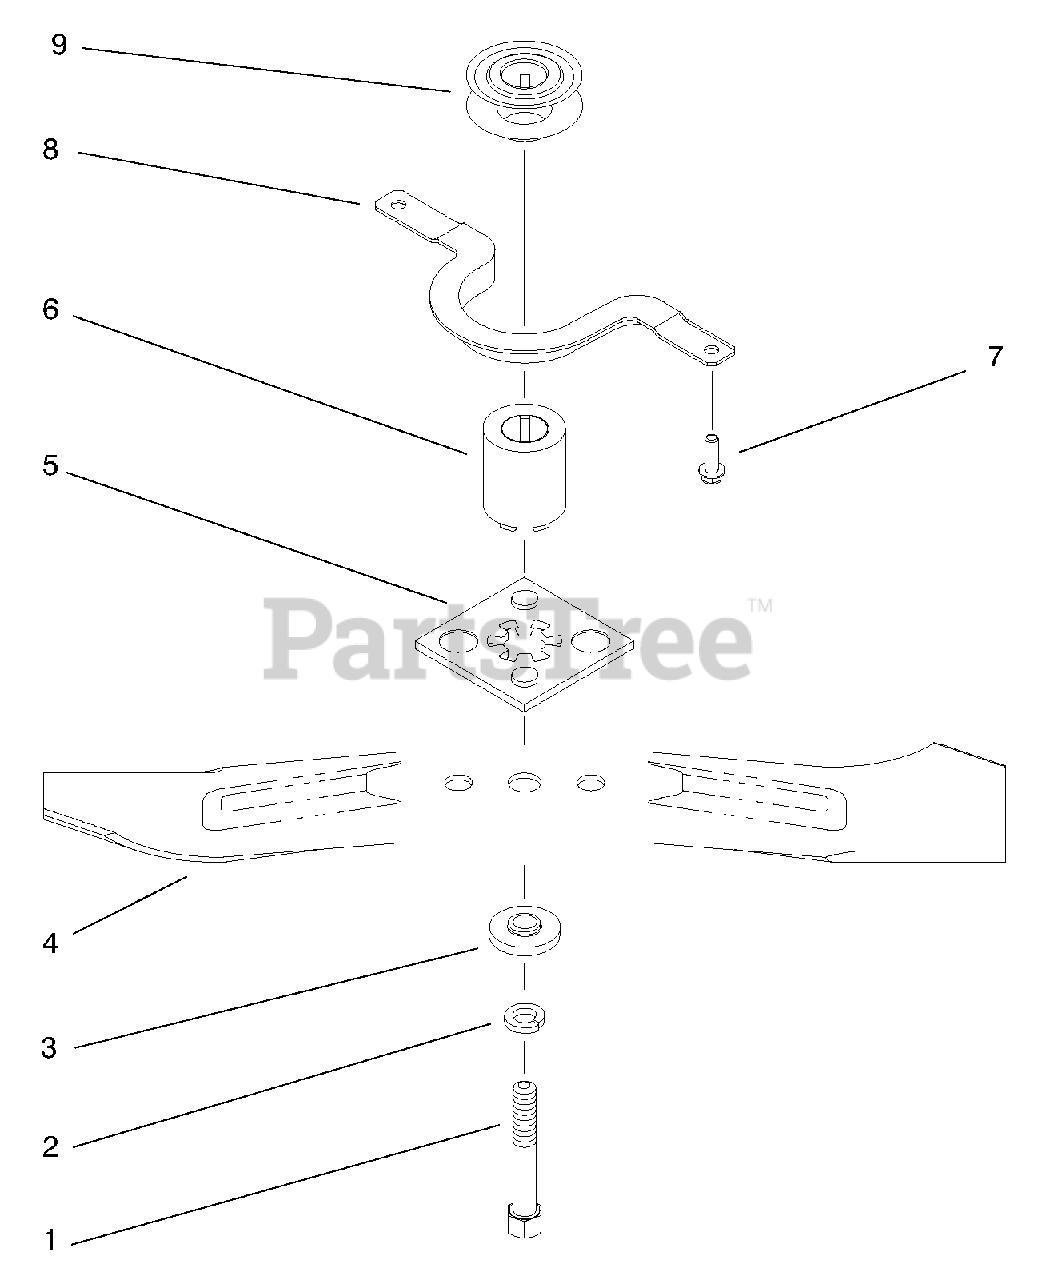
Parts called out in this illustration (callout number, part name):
1	Bolt-Blade
2	Washer-Lock
3	Spacer-Blade
4	Blade 19"
5	Plate-Blade Driver
6	Hub-Blade Driver
7	Screw-HH Tap
8	Guide-Belt Engine
9	Pulley-Driver
